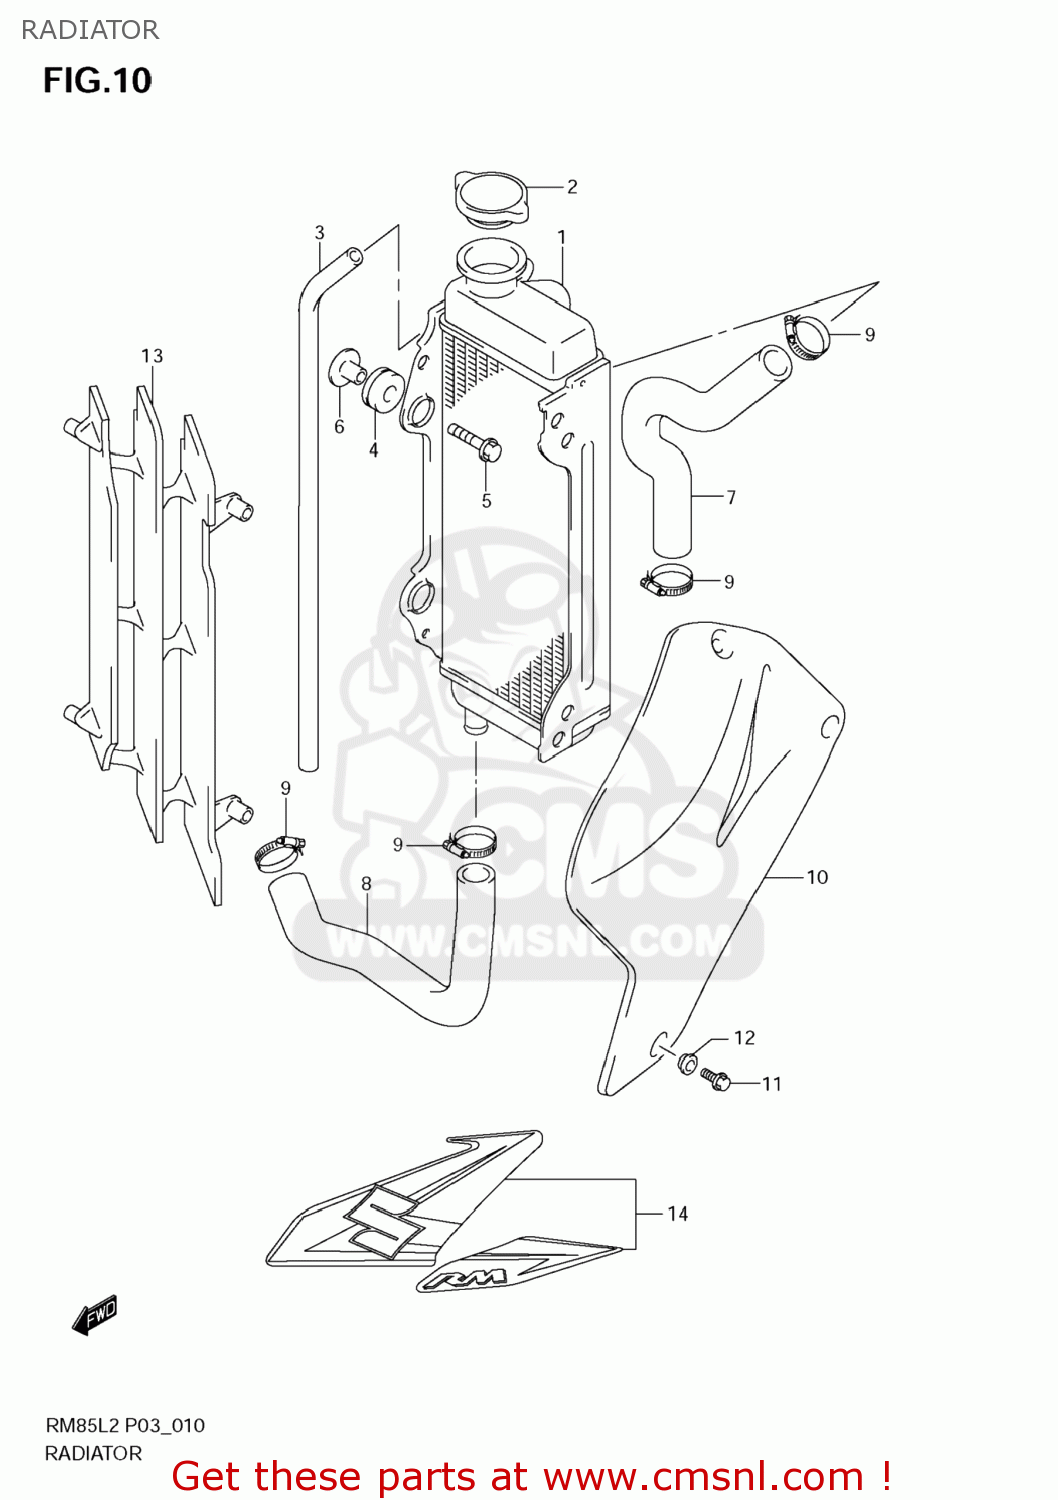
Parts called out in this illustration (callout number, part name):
1	RADIATOR,WATER
2	CAP COMP,RADIATOR
3	HOSE(5X8X1000)
4	CUSHION,RADIATOR LWR
5	BOLT(6X25)
6	SPACER(6.5X10.5X14.1)
7	HOSE,RADIATOR INLET
8	HOSE,RADIATOR OUTLET
9	CLAMP
10	COVER,RADIATOR,L(YELLOW)
11	BOLT(6X12)
12	WASHER
13	LOUVER,RADIATOR
14	TAPE,RADIATOR COVER,L
